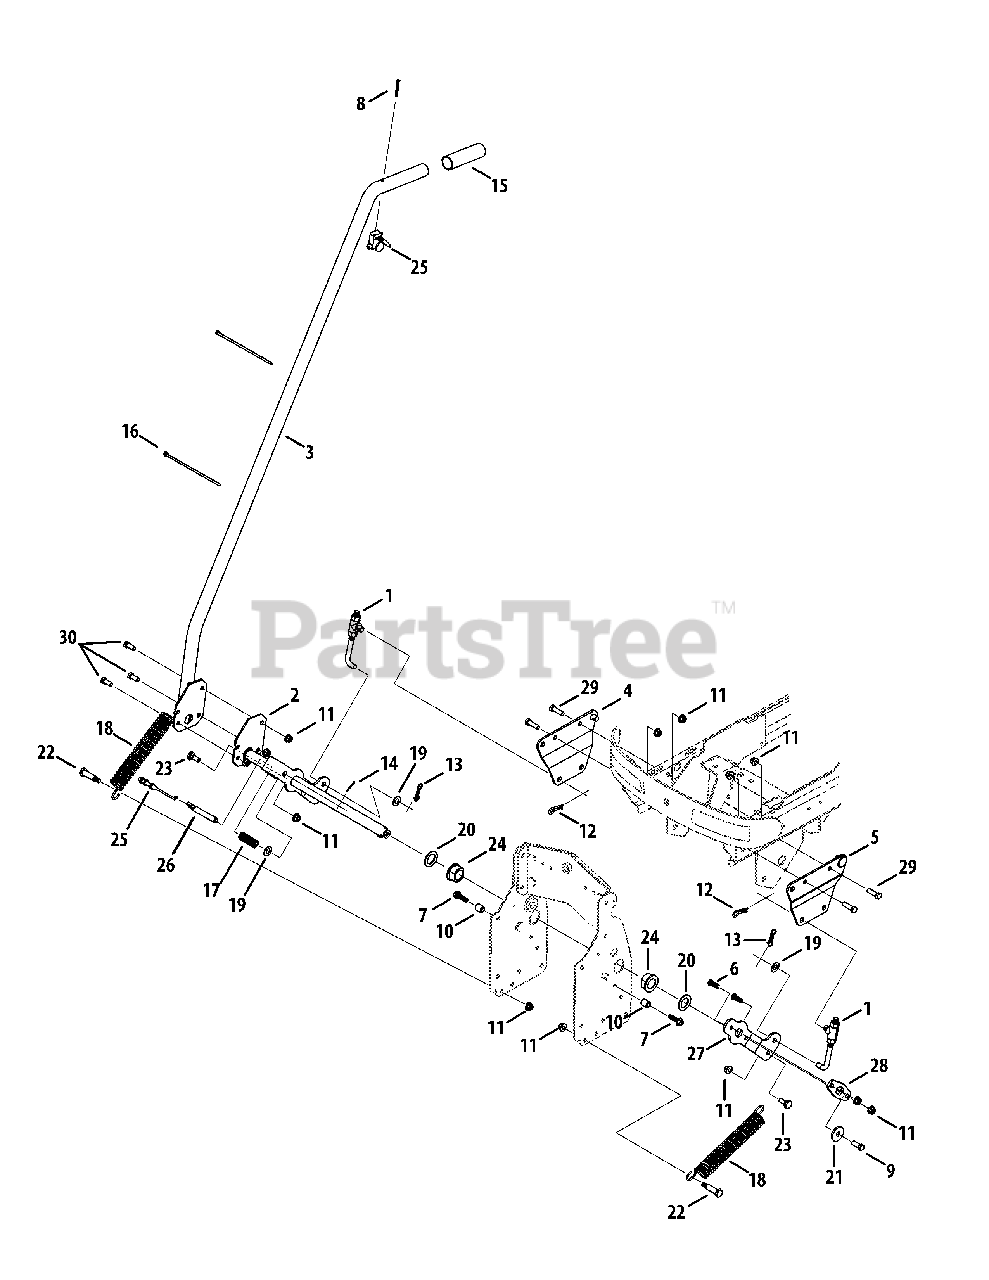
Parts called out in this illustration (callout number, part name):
1	Lift Rod Ferrule
1	Nut, 1/2-13
1	Lift Link Assembly
2	Lift Shaft Assembly
3	Lift Handle Assembly
4	RH Hanger Bracket
5	LH Hanger Bracket
6	Hex Screw, 3/8-16 x 1.00
7	Hex Washer Screw, 3/8-16 x 1.250
8	Oval Screw, #10-24 x 1.75
9	Hex Lock Screw, 3/8-16 x 1.00
10	Spacer, .385 x .623 x .750
11	Flange Lock Nut, 3/8-16
12	Cotter Pin, .125 x 1.75
13	Pin, 7/16-1/2
14	Cotter Pin, 3/32 x 1.25
15	Grip, 1.188 x 4.562
16	Cable Tie, 3/16 x .05 x 7.4
17	Compression Spring, .772 x 1.95
18	Extension Spring, 1.45 x 6.00
19	Flat Washer, .510 x 1.00 x .060
20	Flat Washer, 1.031 x 1.620 x .095
21	Flat Washer, .45 x 1.5 x .172
22	Shoulder Screw, .498 x 1.445
23	Shoulder Bolt, 3/8-16 x .500 x .270
24	Flange Bearing
25	Snowblower Lift Cable
26	Lift Lock Rod
27	Lift Bracket
28	Link Lift Adapter
29	Hex Screw, 3/8-16 x 1.25
30	Hex Screw, 3/8-16 x .880
